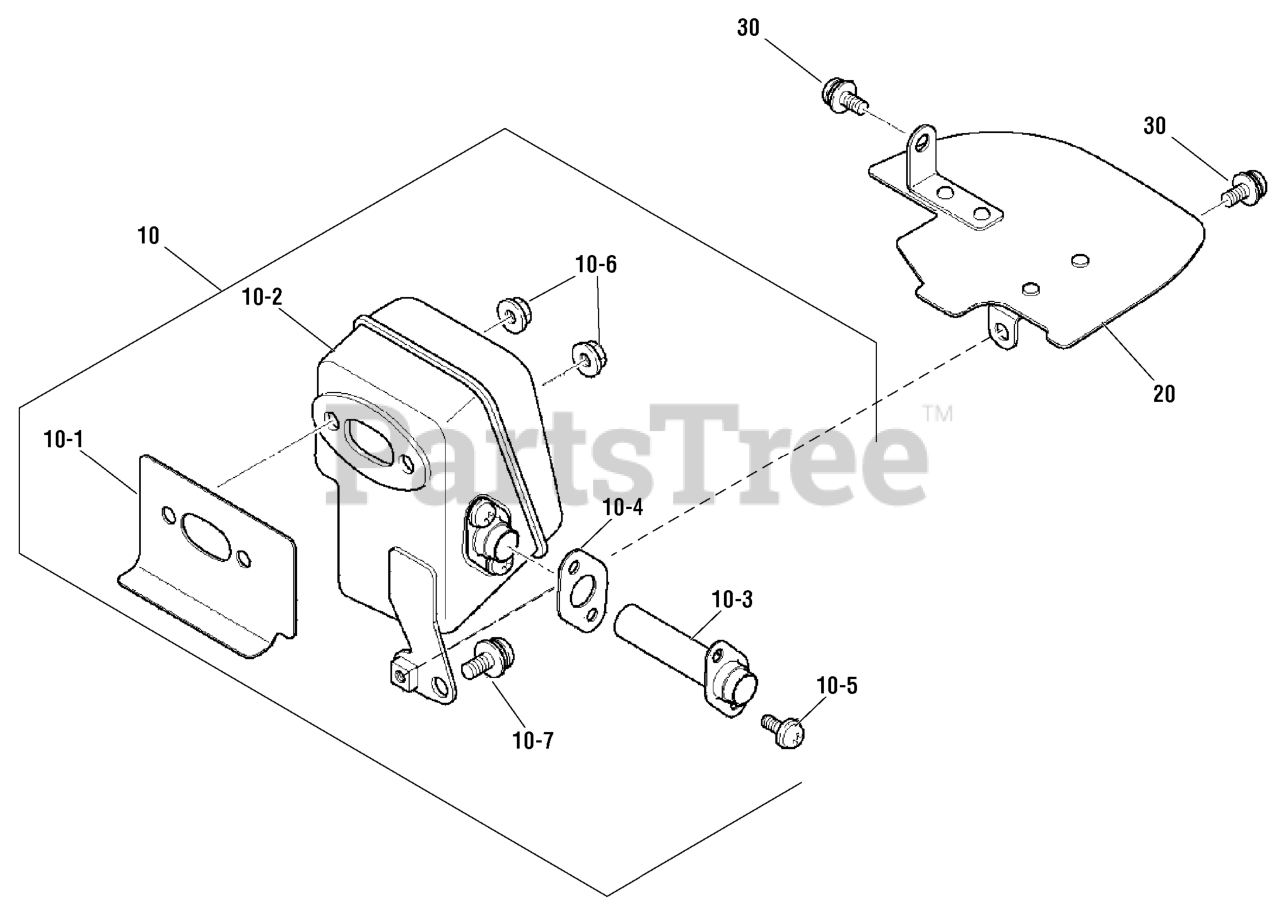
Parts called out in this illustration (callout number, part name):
10	MUFFLER & GASKET KIT
10-1	GASKET, Muffler
10-2	MUFFLER
10-3	TAIL PIPE
10-4	GASKET
10-5	SCREW & WASHER
10-6	NUT, Flange
10-7	SCREW & WASHER
20	GASKET
30	SCREW & WASHER
